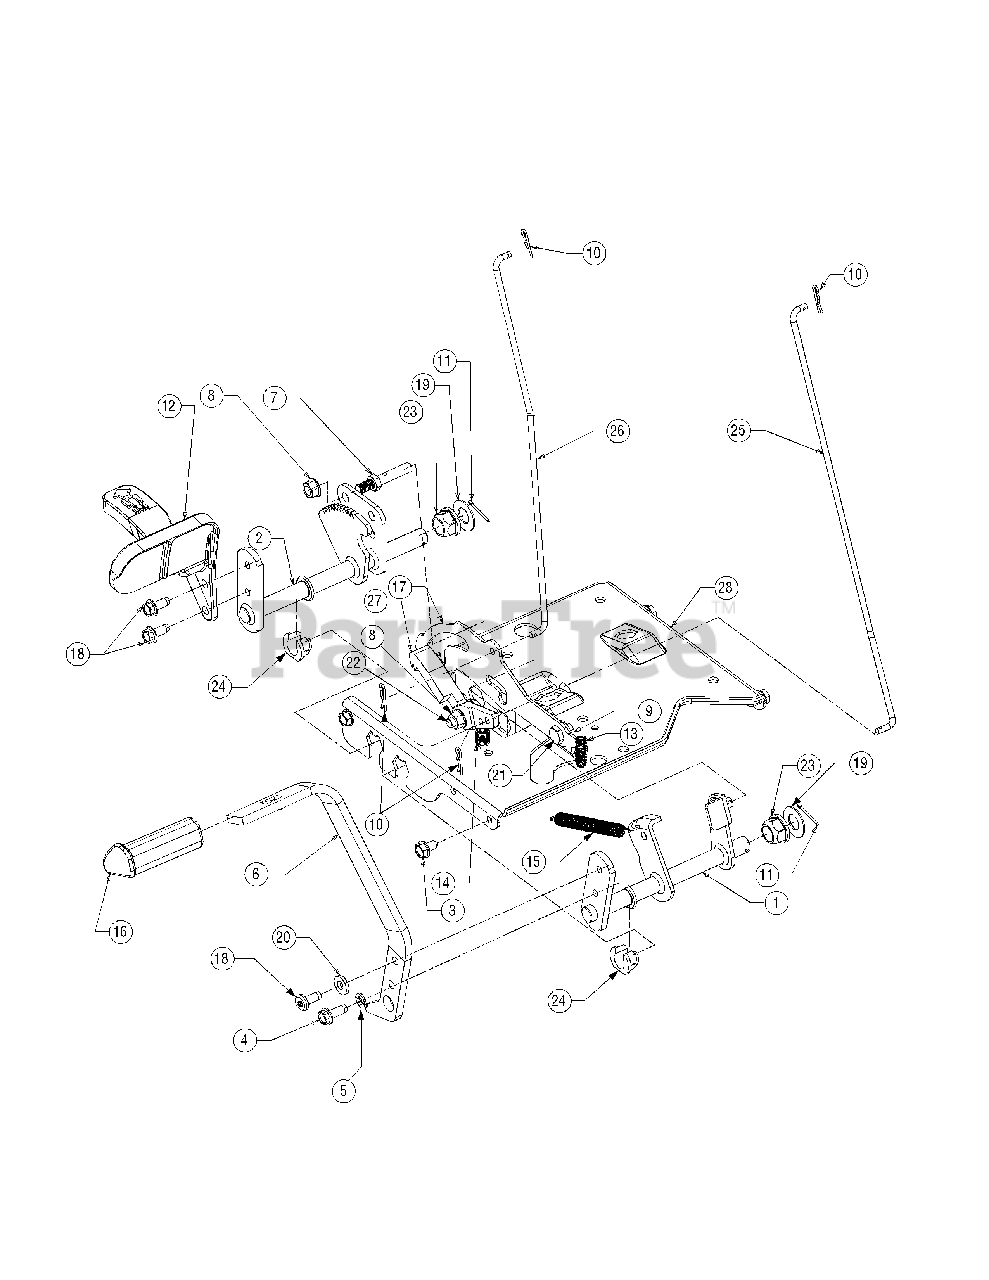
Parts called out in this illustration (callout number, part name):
4	Screw, Self-tapping, 5/16-18, 0.875
5	Washer, Lock, 5/16
8	Nut, Nylon Lock, 3/8-16
9	Nut, Flange Lock, 5/16-18, Gr5
10	Pin, Cotter,.072 Dia. x 1.13 Lg
11	Pin, Cotter, 3/32, 1.0
12	Pedal, Hydro Control
13	Spring, Compression,.405 x 1.17
14	Spring, Extension,.50 OD x 1.41 Lg
15	Spring, Extension,.50 Dia x 6.37 Lg
16	Pad, Brake, Control
17	Bracket, Lockout, Hydro
18	Screw, Torx Hd. Tapp. 5/16-18 x.75
19	Washer, Flat.64 ID x 1.24 x.06
20	Washer, Flat,.344 x.750 x.120
21	Shoulder, Screw.437
22	Shoulder, Screw 3/8-16
23	Bearing, Hex Flange
24	Bearing, Hex Flange,.628 ID, Split
25	Rod, Control, Cruise
26	Rod, Control, Brake Lock
27	Latch, Cruise
